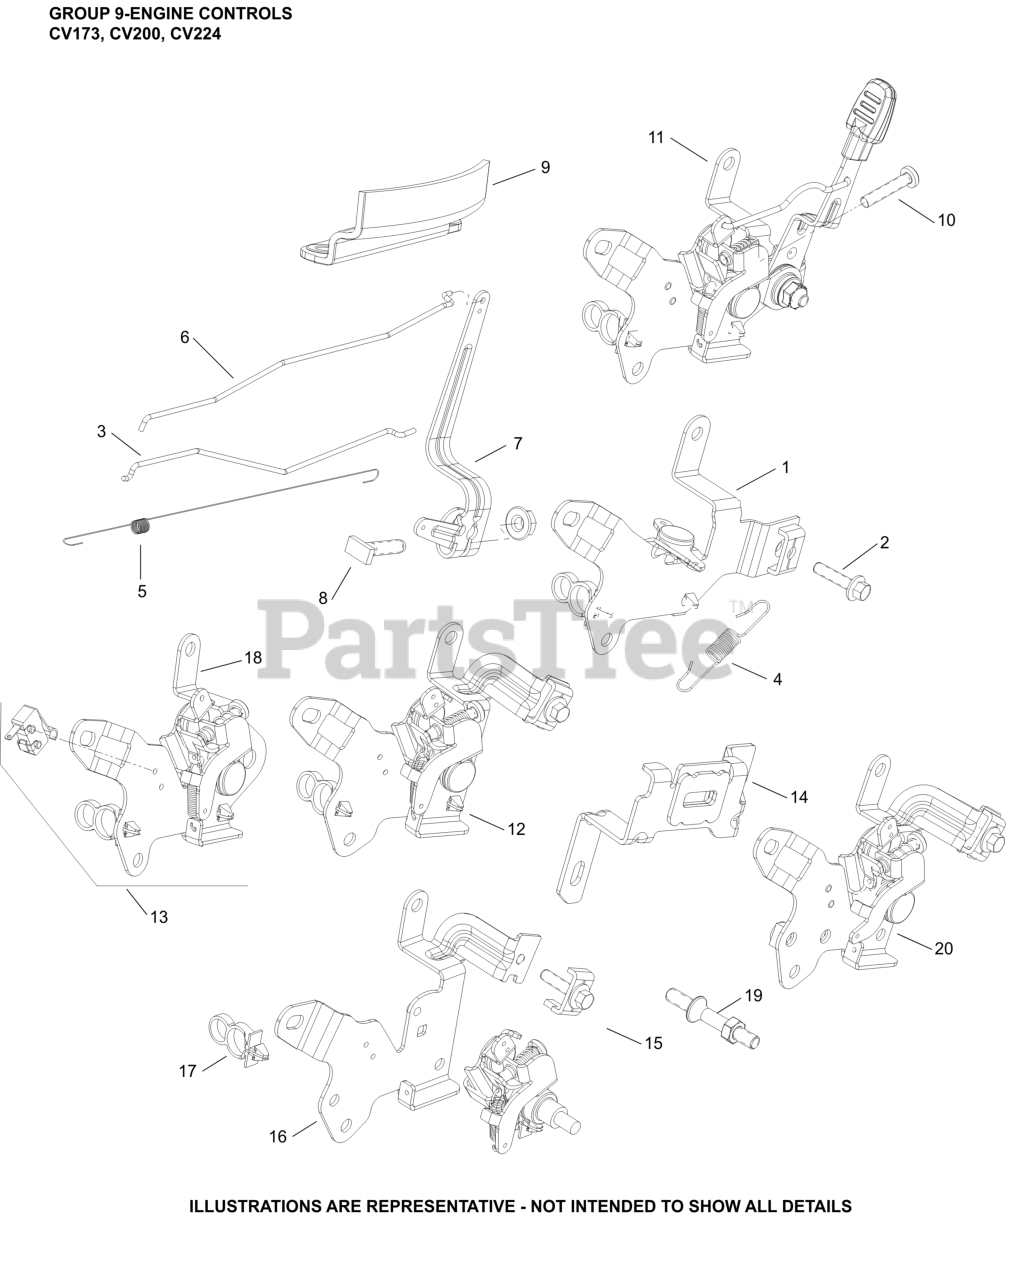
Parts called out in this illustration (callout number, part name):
3	LINKAGE, CHOKE
4	SPRING, GOVERNOR
5	SPRING, LINKAGE
6	LINKAGE, GOVERNOR
7	LEVER, GOVERNOR-USE 14 090 37-S
8	SCREW, RECTANGLE HEAD (M6)
9	GUARD, FINGER
10	SCREW, SPEED ADJUSTING
11	CONTROL ASSEMBLY, NON-REMOTE V SPED W
